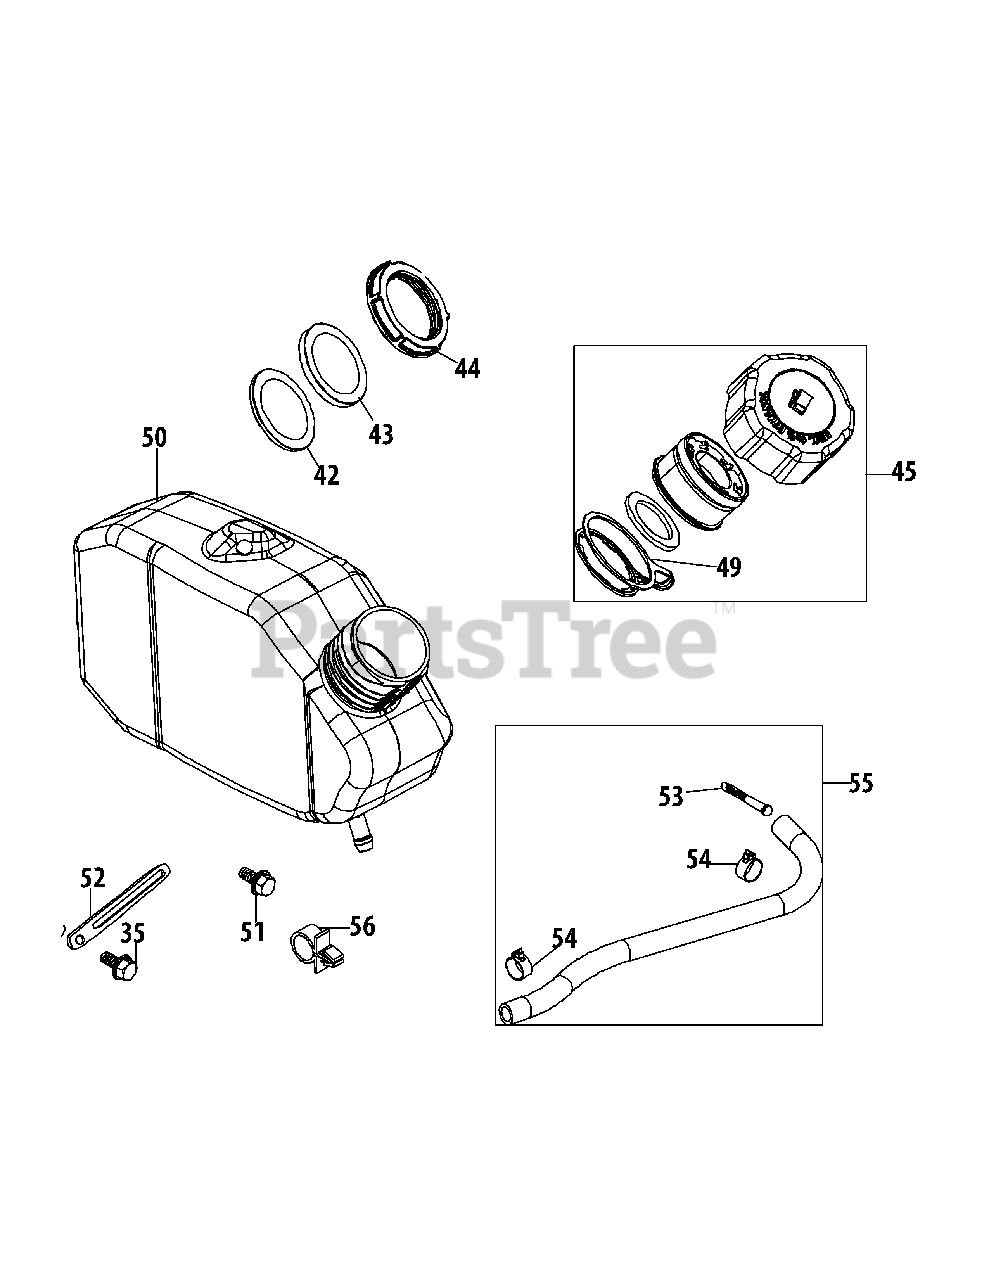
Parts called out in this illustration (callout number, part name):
35	Bolt M6X14 Multi-Purpose
42	Fuel Tank Lower Grommet
43	Fuel Tank Upper Grommet
44	Fuel Tank Nut
45	Fuel Cap Assembly
49	Fuel Cap Tether
50	Fuel Tank
51	Bolt M6X12 Multi-Purpose
52	Flexible Clamp, Vent Hose
53	Fuel Filter
54	Fuel Hose Clamp
55	Fuel Hose
56	Plastic Support Clamp
